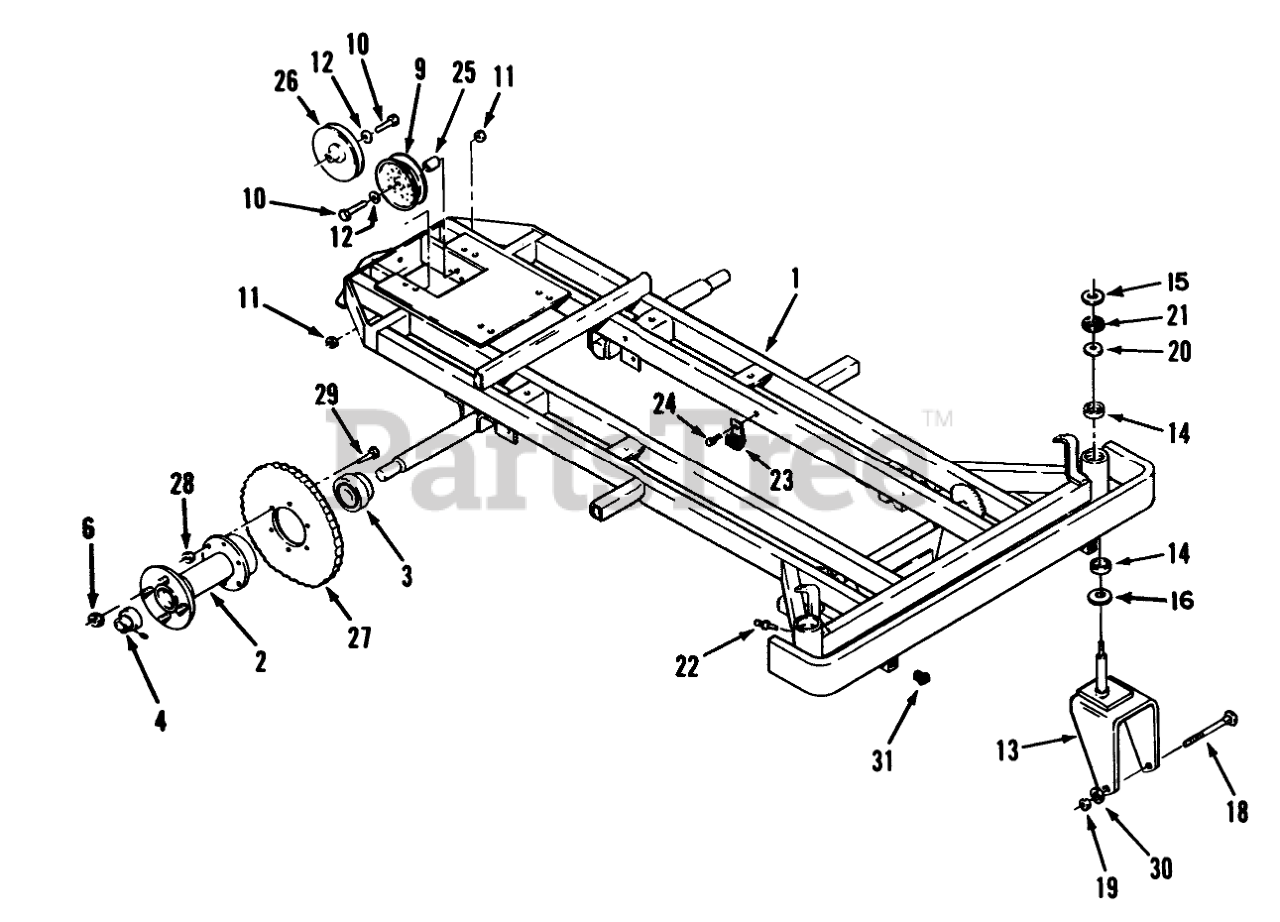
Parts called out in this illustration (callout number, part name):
1	WLDMT-FRAME B
2	Hub-Rear Wheel
3	BEARING-REAR AXLE
4	BEARING-REAR AXLE
6	Nut-Lug 1/2-20
9	PULLEY FLAT B
10	SCREW-HH
11	NUT-LOCK, NI
12	WASHER-FLAT
13	Fork-Front Wheel
14	BUSHING-PIVOT
15	RING-RETAINING
16	WASHER-THRUST
18	SCREW-HH
19	NUT-HEX
21	WASHER-THRUST
22	ZERK FITTING
23	CLIP
24	Bolt
25	BUSHING
26	PULLEY-IDLER V
27	SPROCKET-REAR HUB B
28	NUT-LOCK, NI
29	SCREW-HH
30	WASHER-LOCK
31	PLUG-SQUARE PLASTIC
